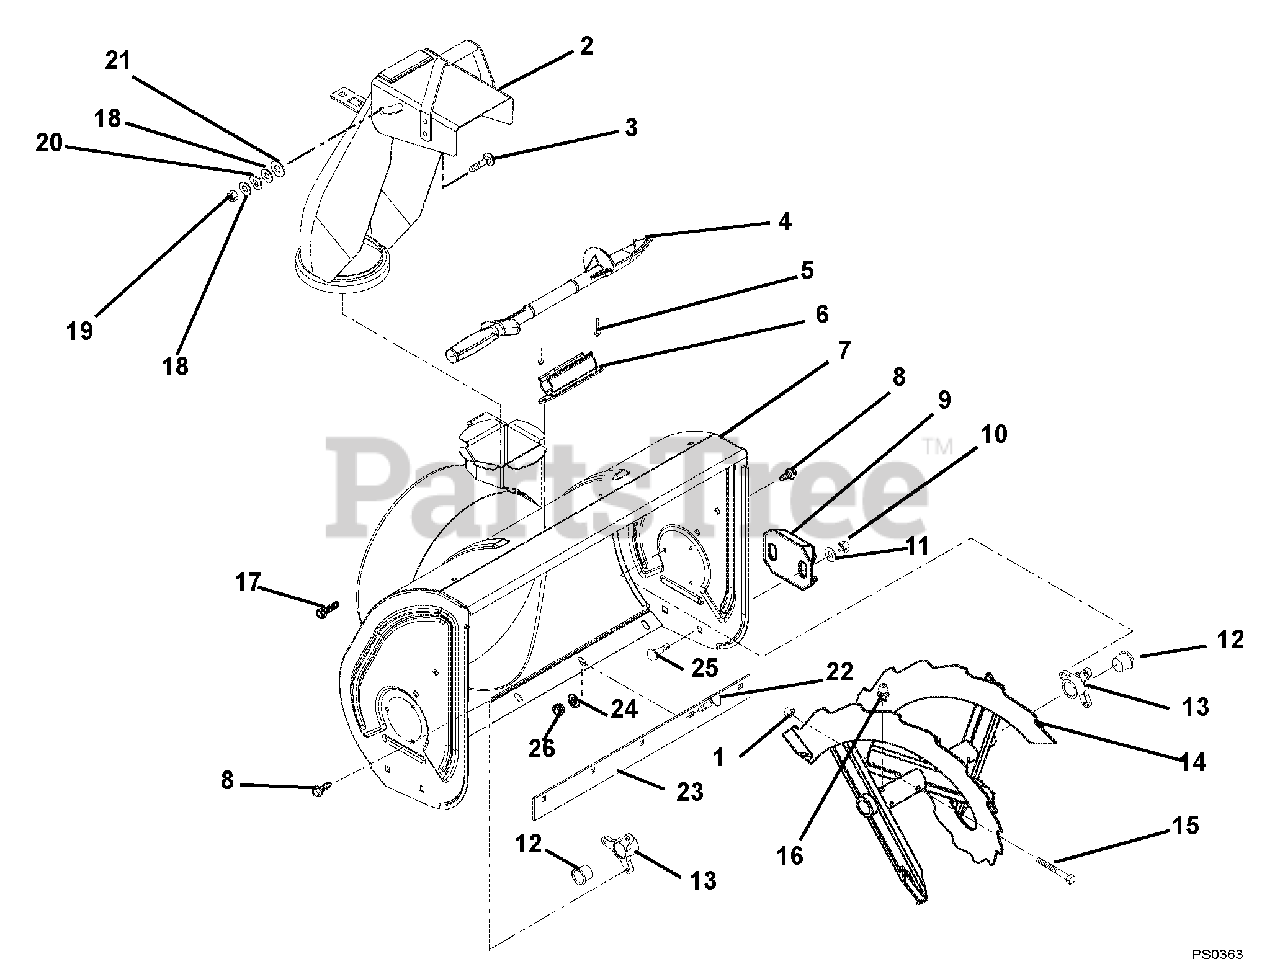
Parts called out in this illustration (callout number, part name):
1	@NUT-LK-CTR .25-20 YWZC
2	CHUTE, DISCHARGE W/CAP & DECAL
3	@BLT-RHDSSQNK .31-18X.75 G5YZ
4	DEVICE, SNOW CLEAN OUT
5	RVT-POP .187 YZ
6	MOUNT, SNOW CLEAN OUT
7	BLOWER HOUSING, 24"
7	BLOWER HOUSING, 20"
8	@SCR-TAP .25-20X.50 HWH TR YWZ
9	SKID SHOE, REVERSIBLE - ORANGE
10	@NUT-LK-CTR .38-16 YWZC
11	@WSHR-FL-STL.38X.875X.083 YWZC
12	BSHG-FLG SPLIT NYLINER .75"ID
13	BUSHING, RAKE SHAFT .75"
14	RAKE, 24" RH, BLK SERR W/ZERK
14	RAKE, 24" LH, BLK SERR W/ZERK
14	AUGER, 20" RH, BLK SERR W/ZERK
14	AUGER, LH 20", BLK SERR W/ZERK
15	SHEAR BOLT WITH NUT
16	ZERK,FITTING .25X.125 DRIVE IN
17	@SCR-TAP .38-16X.50 HWH TR YWZ
18	@WSHR-FL-STL.344X.688X.065YWZC
19	@NUT-LK-CTR .31-18 YWZC
20	WAVE WASHER .390X.655X.110
21	WSHR-PLASTIC .390X.875X.062
22	@BLT-RDHDSQNK .31-18X.50 G5YZ
23	BLADE, SCRAPER - 24" COMPACT
24	@WSHR-FL-STL.344X.688X.065YWZC
25	@BLT-RHDSSQNK .38-16X.75 G5YZ
26	@NUT-LK-CTR .31-18 YWZC
